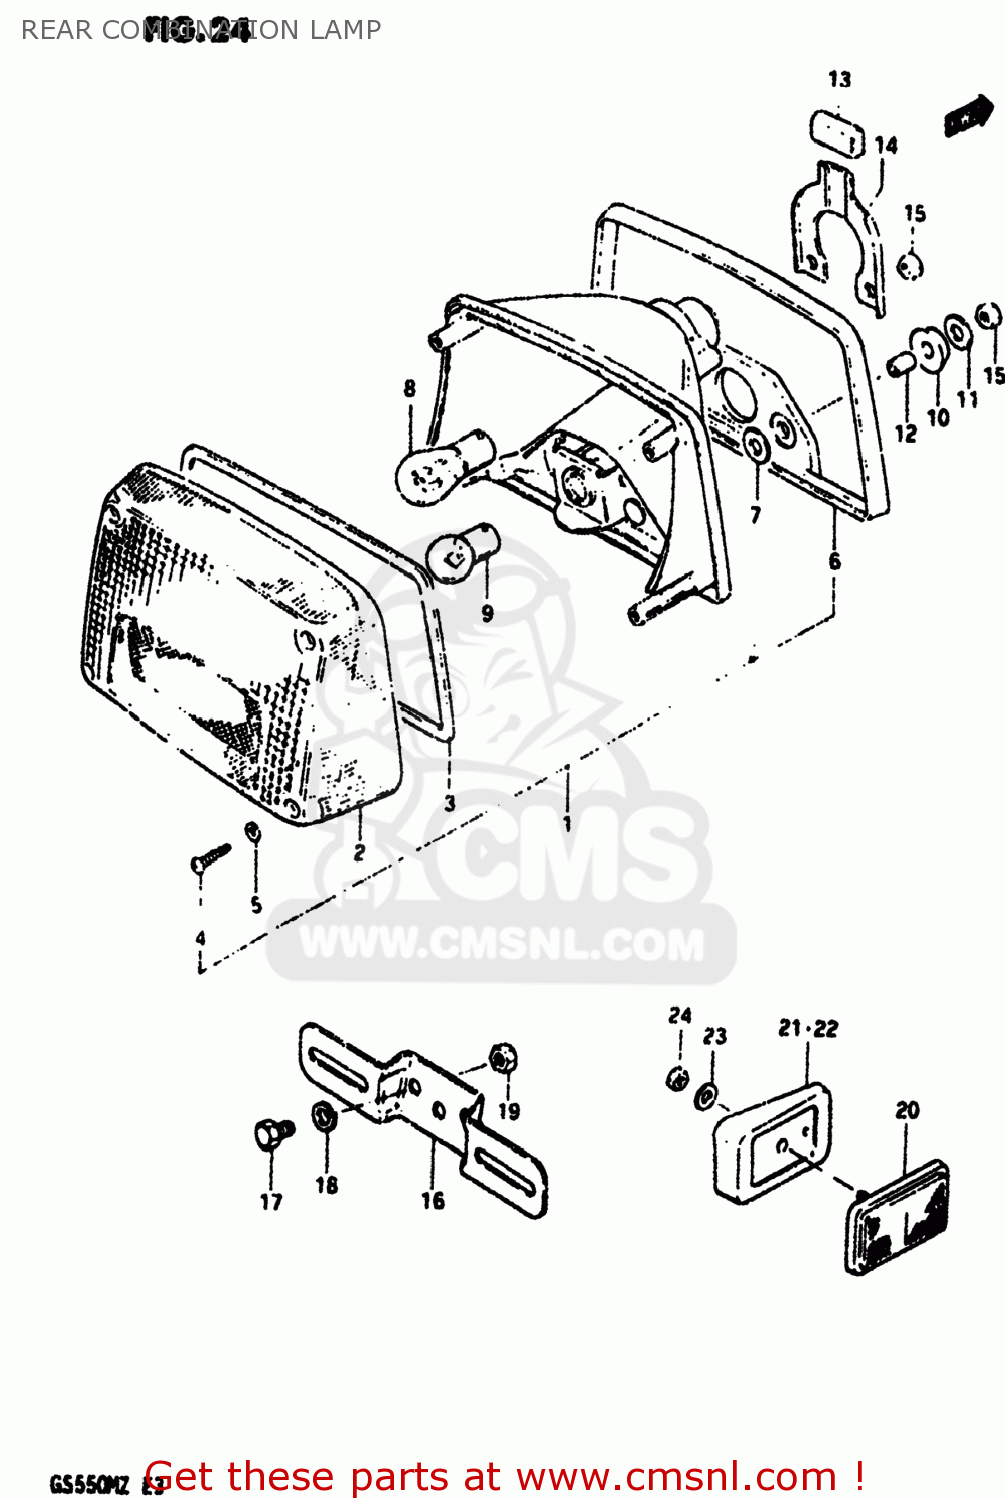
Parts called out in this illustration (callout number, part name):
1	LAMP ASSEMBLY,REAR COMBINATION
2	LENS
3	GASKET (NAS)
4	SCREW,REAR COMBINATION LAMP
5	GASKET (NAS)
6	CUSHION,REAR COMBINATION LAMP
7	WASHER,REAR COMBINATION LAMP
8	BULB(12V23W)
9	BULB
10	CUSHION,RR COMBINATION LAMP
11	WASHER
12	SPACER (6.4X9X10.5)
13	CUSHION,REAR COMBINATION LAMP
14	PLATE
15	NUT 6MM
16	BRACKET,LICENSE PLATE
17	BOLT
18	LOCK WASHER
19	NUT
20	REFLECTOR,REFLEX
21	SPACER,REAR REFLEX REFLECTOR
22	SPACER,REAR REFLEX REFLECTOR
23	WASHER(5.2X16X1)
24	NUT
